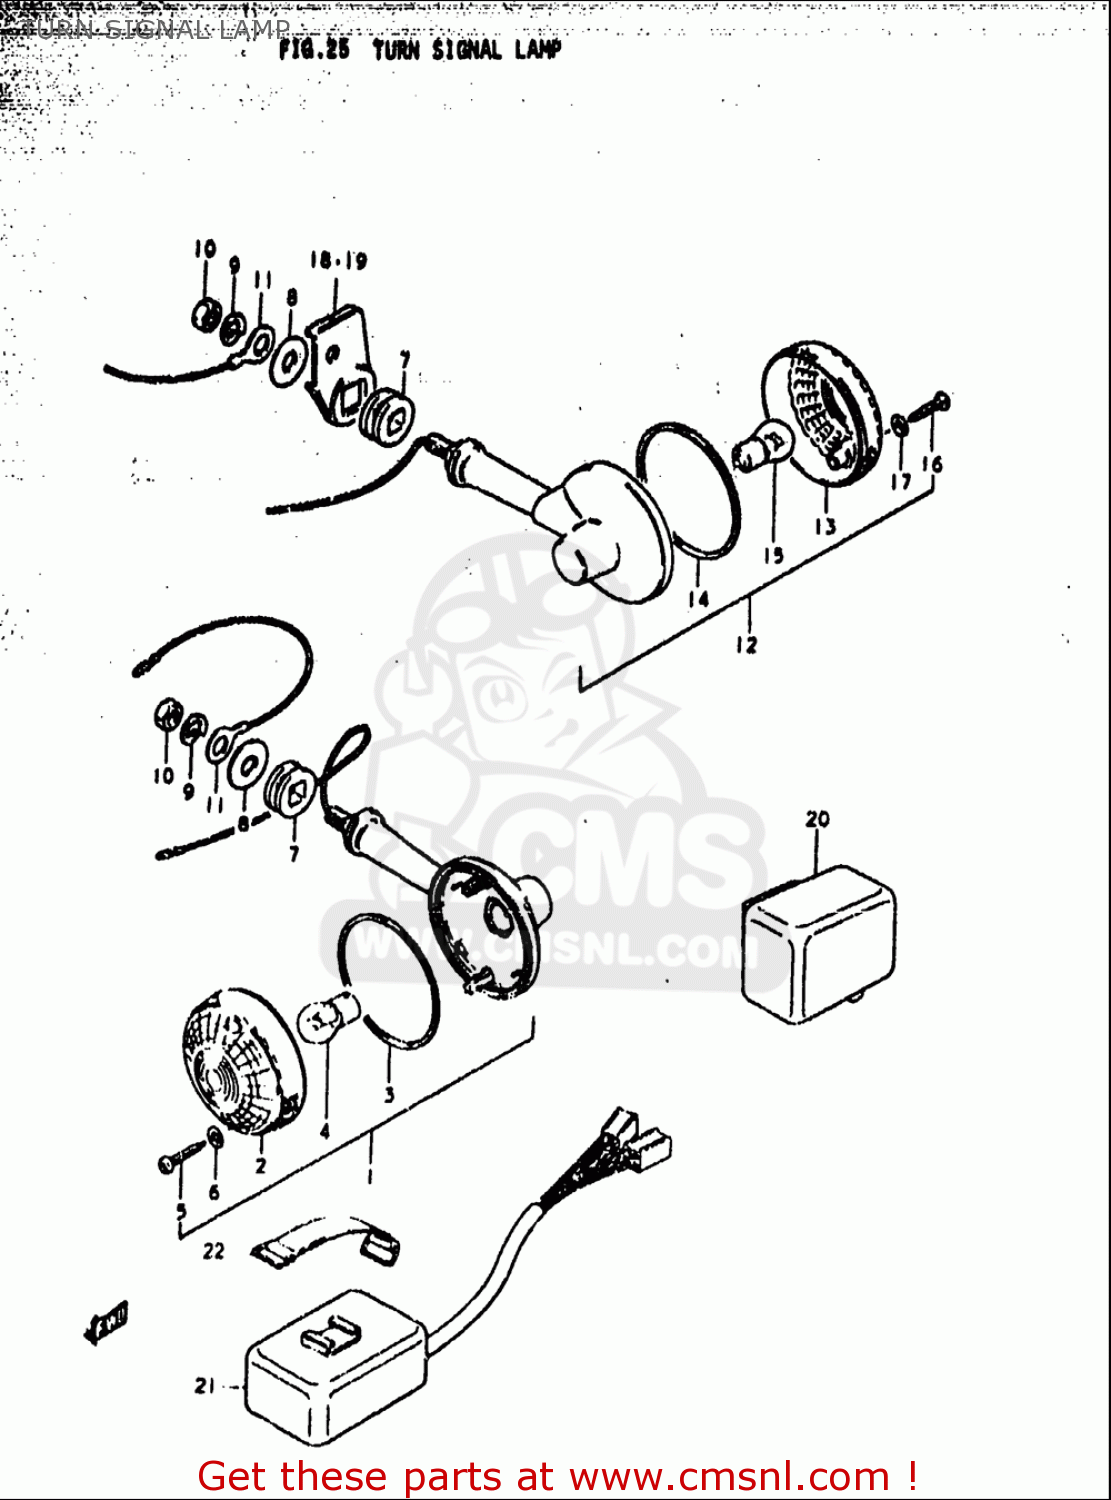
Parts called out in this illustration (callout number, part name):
1	LAMP ASSY,RR TURNSIGNAL
2	LENS
3	GASKET (NAS)
4	BULB(12V23W,STANLEY,A4577A)
5	SCREW
6	GASKET (NAS)
7	CUSHION
8	WASHER (8.5X30X2.3)
9	WASHER,LOCK
10	NUT
11	LEAD WIRE,EARTH
12	LAMP ASSY,RR TURNSIGNAL
13	LENS
14	GASKET (NAS)
15	BULB(12V23W,STANLEY,A4577A)
16	SCREW
17	GASKET (NAS)
18	BRACKET,RR TURNSIGNAL LAMP,R
19	BRACKET,RR TURNSIGNAL LAMP,L
20	RELAY ASSY,TURNSIGNAL
21	TURNSIGNAL CONTROL UNIT
22	BAND
